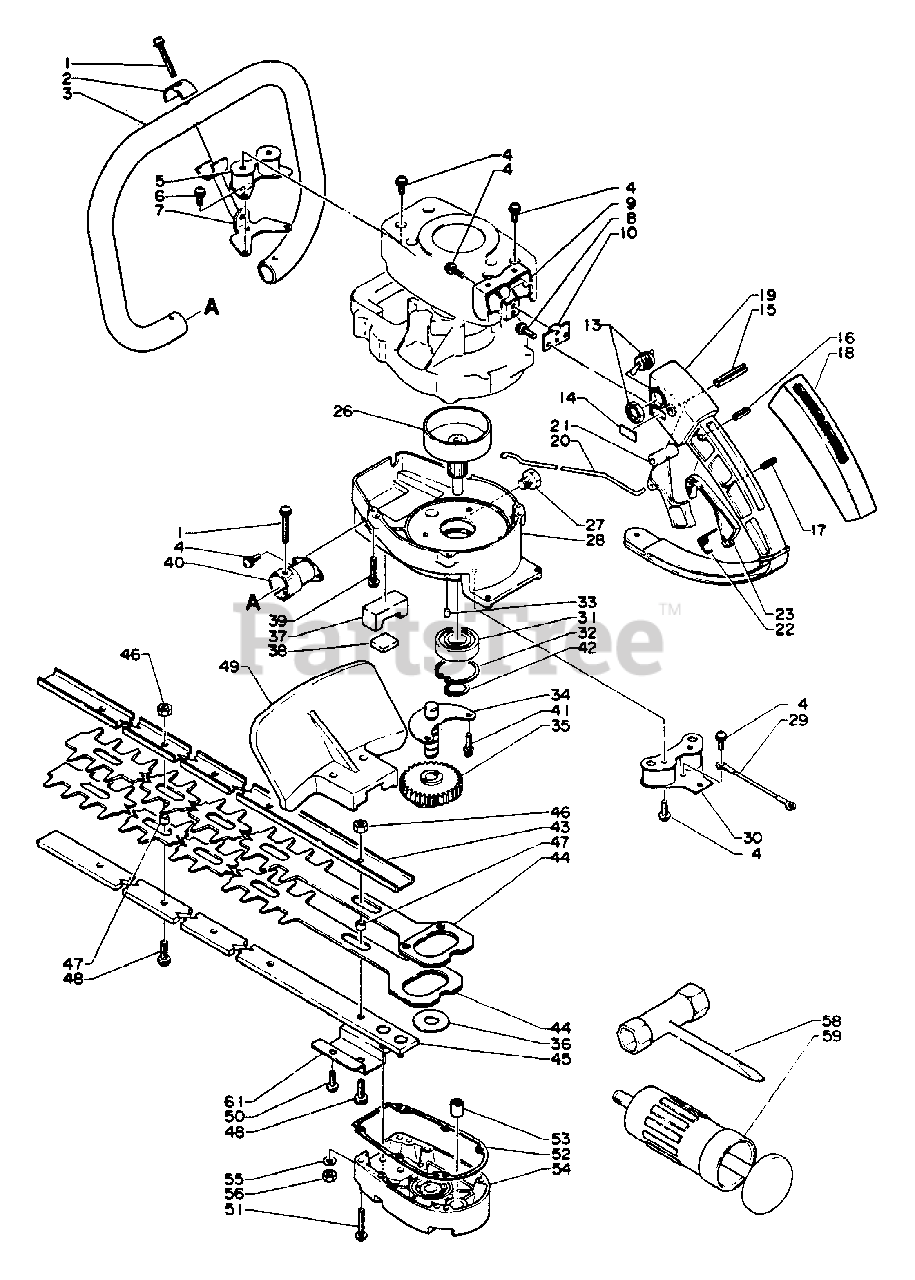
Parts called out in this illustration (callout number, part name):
1	SCREW 4×30
3	HANDLE, FRONT
4	SCREW 4×12
6	SCREW 4×8
8	SCREW 4×12
10	PLATE
13	SWITCH, ON-OFF
14	LABEL, ON-OFF
15	PIN, SPRING 5×32
16	PIN, SPRING 4×16
17	PIN, SPRING 3×14
19	HANDLE
20	ROD, THROTTLE
21	TRIGGER, THROTTLE
22	SPRING, TORSION
23	LOCKOUT, THROTTLE
26	DRUM, CLUTCH
27	BOLT 8×8 SP
28	CASE, GEAR
29	LEAD - GROUND
30	CUSHION
31	BEARING, BALL 6003
32	RING, SNAP 35
33	PIN, LOCATING 4
34	SHAFT GEAR ASSY
35	GEAR SHAFT ASSY
36	SEAT, CAM
37	SEAL, FELT
38	SEAL, FELT
39	SCREW 4×22
40	CUSHION
41	BOLT 4×14
42	RING, RETAINING - 16
43	FRAME BAR
44	TRIMMER BLADE SET
44	UPPER OR LOWER BLADE
45	BAR, FRAME - LOWER
46	LOCKNUT - 5
47	SPACER
48	BOLT M5×18
49	GUARD
50	SCREW 5×12
51	SCREW 4×25
52	GASKET, GEAR CASE
53	BEARING, NEEDLE
54	LID, GEAR CASE
55	WASHER, FLAT 5.5×10×0.8
56	LOCKNUT - 5
58	T-WRENCH
59	PUMP, GREASE
61	BRACKET
